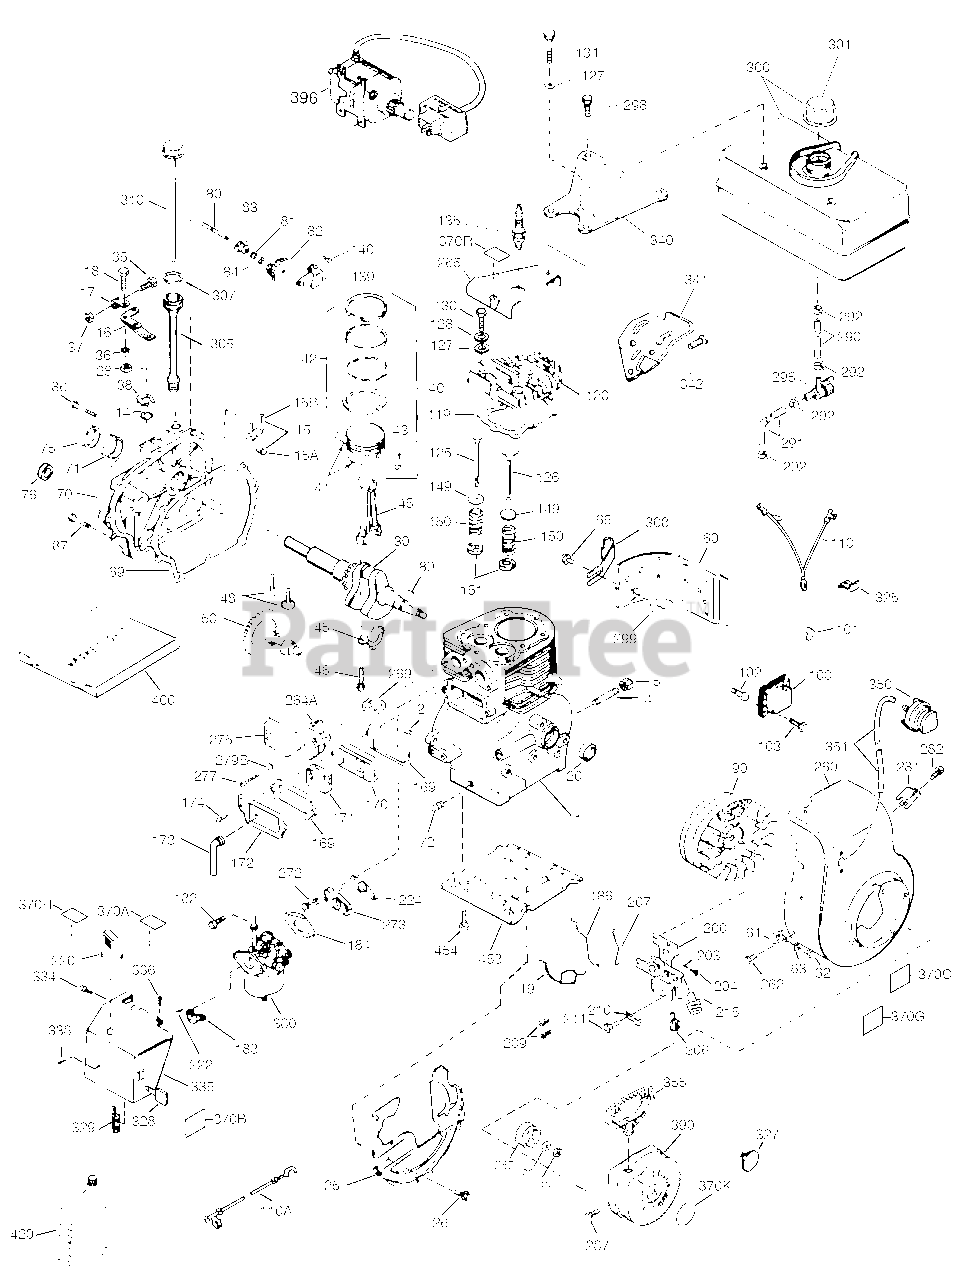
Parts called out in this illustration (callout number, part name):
1	"Cylinder (Incl. 2, 20 & 72)
2	Dowel Pin
14	Flat Washer
15	Governor Rod (Incl. 15A & 15B)
15A	Governor Yoke
15B	Screw, 6-40 x 5/16"
16	Governor Lever
17	Governor Lever Clamp
18	Screw, T-15, 8-32 x 7/16"
19	Speed Control Spring
20	Oil Seal
25	Blower Housing Baffle
26	Screw, 1/4-20 x 19/32"
28	Lock Nut, 8-32
30	Crankshaft
35	Screw, 10-32 x 3/4"
36	Lock Washer #8
37	Lock Nut, 10-32
38	Retaining Ring
40	Piston, Pin & Ring Set (Std.)
40	Piston, Pin & Ring Set (.010" OS)
40	Piston, Pin & Ring Set (.020" OS)
41	Piston & Pin Ass'y (Std.) (Incl. 43)
41	Piston & Pin Ass'y (.010" OS) Incl. 4 3
41	Piston & Pin Ass'y (.020" OS) Incl. 4 3
42	Ring Set (Std.)
42	Ring Set (.010" OS)
42	Ring Set (.020" OS)
43	Piston Pin Retaining Ring
45	Connecting Rod Ass'y (Incl. 46)
46	Connecting Rod Bolt
48	Valve Lifter
50	Camshaft (MCR)
60	Blower Housing Extension
65	Screw, 10-24 x 1/2"
69	* Cylinder Cover Gasket
70	Cylinder Cover (Incl. 71, 75 & 80)
71	Crankshaft Bushing
72	Oil Drain Plug (Sq. hd., 1/4-18)
75	Oil Seal
80	Governor Shaft
82	Governor Gear Ass'y (Incl. 81)
83	Governor Spool
84	Retaining Ring
86	Screw, 1/4-20 x 1-1/4"
87	Screw, 1/4-20 x 1-3/4"
89	Flywheel Key
90	Flywheel
92	Belleville Washer
93	Flywheel Nut
100	Solid State Ignition (Incl. 101)
101	Spark Plug Cover
102	Solid State Mounting Stud
103	Screw, T-15, 10-24 x 15/16"
110	Ground Wire
110A	Ground Wire (10.50" with male & femal e flag terminals)
119	* Cylinder Head Gasket
120	Cylinder Head (Incl. 3 of 130)
125	Exhaust Valve (Std.)(Incl. 151)
125	Exhaust Valve (1/32" OS) (Incl. 151)
126	Intake Valve (Std.) (Incl. 151)
126	Intake Valve (1/32" OS) (Incl. 151)
128	Belleville Washer
130	Screw, 5/16-18 x 2-1/2"
130A	Screw, 5/16-18 x 2-1/2"
130B	Screw, 5/16-18 x 2-1/2"
135	Resistor Spark Plug (RJ19LM) also ava ilable in Packaged Part #740081
139	Governor Gear Bracket
140	Screw, T-25, 10-24 x 1/2"
149	Valve Spring Cap
150	Valve Spring
151	Valve Spring Keeper
169	* Valve Cover Gasket
170	Breather Body
171	Breather Element
172	Valve Cover
173	Breather Tube
174	Screw, 10-24 x 1/2"
182	Screw, T-30, 1/4-20 x 27/32"
183	Choke Bracket
184	* Carburetor To Intake Pipe Gasket
186	Governor Link
200	Control Bracket (Incl. 203,204 & 206)
203	Compression Spring
204	Screw, T-10, 5-40 x 7/16"
206	Terminal
207	Throttle Link
209	Screw, 10-32 x 1/2"
215	Control Knob
220	Control Knob
222	Screw, 10-32 x 1/2"
224	* Intake Pipe Gasket
260	Blower Housing
262	Screw, T-40, 5/16-24 x 21/32"
264A	Screw, 5/16-18 x 3/4"
265	Cylinder Head Cover
269	* Exhaust Gasket
272	Screw, 5/16-18 x 3/4"
273	Carburetor Flange (Incl. 182)
275	Muffler
277	Screw, 5/16-18 x 2"
285	Starter Cup
287	Screw, 8-32 x 21/64"
290	Fuel Line (8.62")
291	Fuel Line
292	Fuel Line Clamp
295	Fuel Shut-Off Valve (Incl. 292) also available in Packaged Part #740073
298	Screw, 1/4-15 x 3/4"
299	"U" Type Nut
300	Fuel Tank (Incl. 292 & 301)
301	Fuel Cap
305	Oil Fill Tube
307	"O" Ring
308	Fill Tube Clip
310	Dipstick
325	Wire Clip
328	Ignition Key (also available in Packa ged Part #740077)
334	Screw, 8-32 x 5/16"
335	Carburetor Cover
336	Screw, 10-32 x 1/2"
338	Screw, 8-32 x 3/8"
340	Fuel Tank Bracket
341	Fuel Tank Bracket
342	Screw, 1/4-20 x 19/32"
343	Key Switch Bracket (Incl. 343A)
343A	Screw, 10-32 x 23/64"
350	Primer Assembly (also available in Pa ckaged Part #740101)
351	Primer Line
355	Starter Handle (Mitten Grip) also ava ilable in Packaged Part #740053B
361	Screw, T-30, 1/4-20 x 15/32"
370C	Primer Decal
370G	Instruction Decal
370H	Choke Decal
370K	Starter Decal
370R	Warning Decal (Bilingual)
380	Carburetor (Incl. 184)
390	Rewind Starter
396	Electric Starter Motor (120 Volt)
400	* Gasket Set Incl. items marked PK in n otes
420	SAE 5W30 4-Cycle Engine Oil - Quart - Winter
453	Engine Mounting Base
454	Screw, 5/16-18 x 3/4"
999	Winter Maintenance Kit incl. 5W30 Oil , Spark Plug, Key, & Ultra-Fresh
999	Winter Maintenance Kit (incl. 0W30 Sy nthetic Oil, Spark Plug, Key, & Ultra -Fresh)
